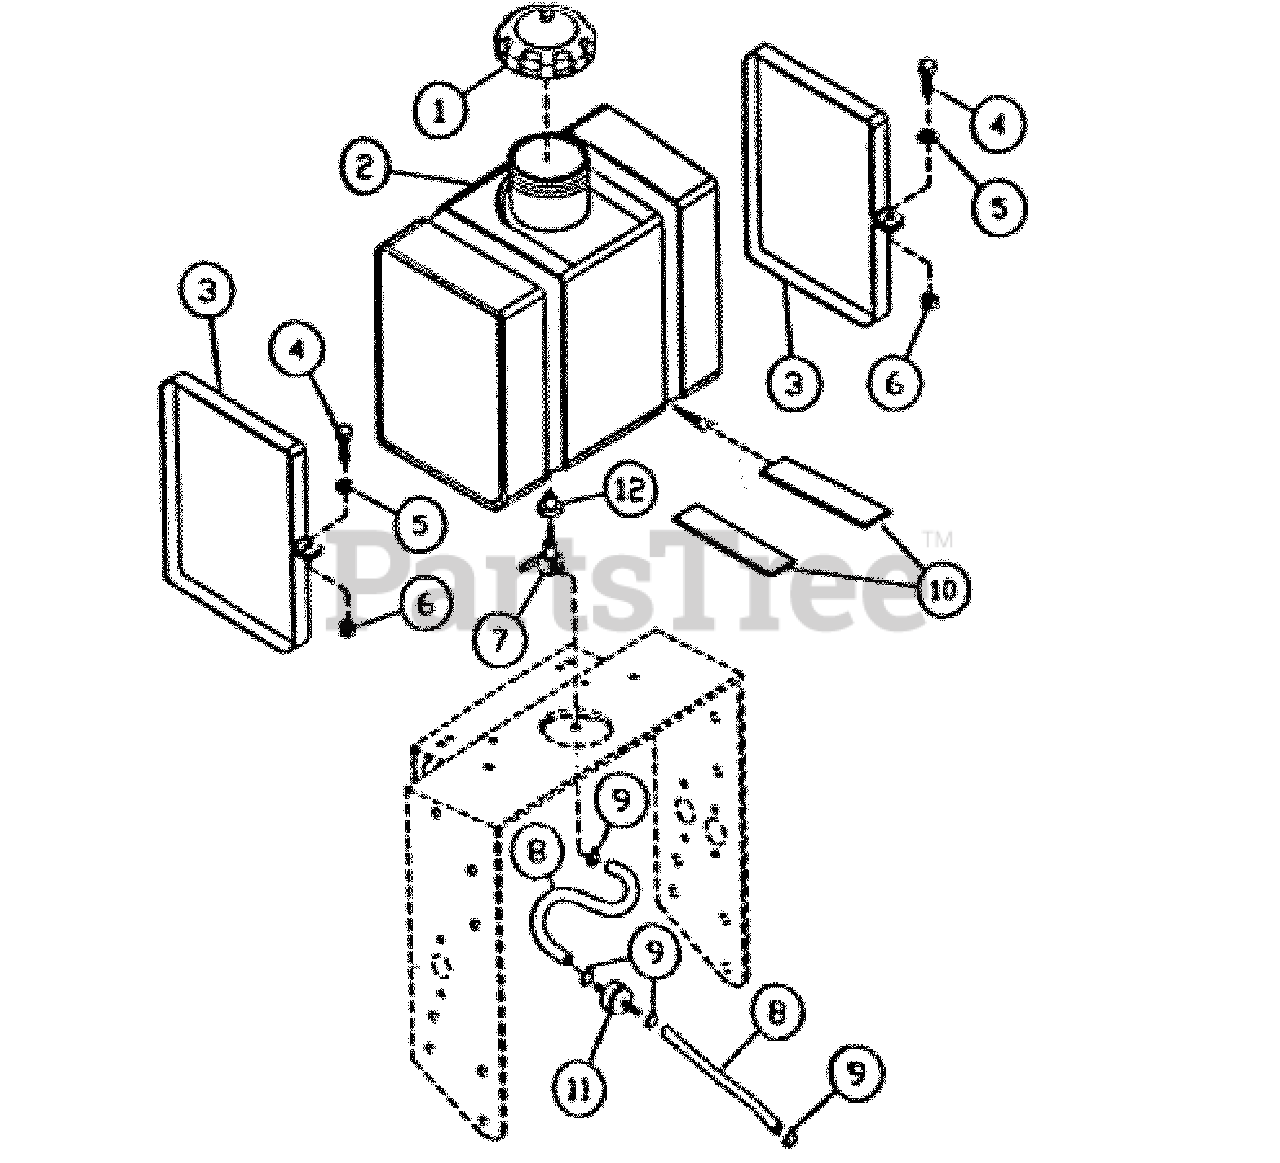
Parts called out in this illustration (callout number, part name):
1	100-102 FUEL TANK CAP
2	100-103 FUEL TANK BODY
4	10PK HEXAGON BOLT
5	WASHER, 3/16 STD FLAT
6	200-009 NYLON NUT M6
7	100-105 FUEL SHUT OFF
8	100-106 FUEL LINE
9	FUEL LINE CLAMP
11	100-108 FUEL FILTER
12	100-109 TUBE INSERT
